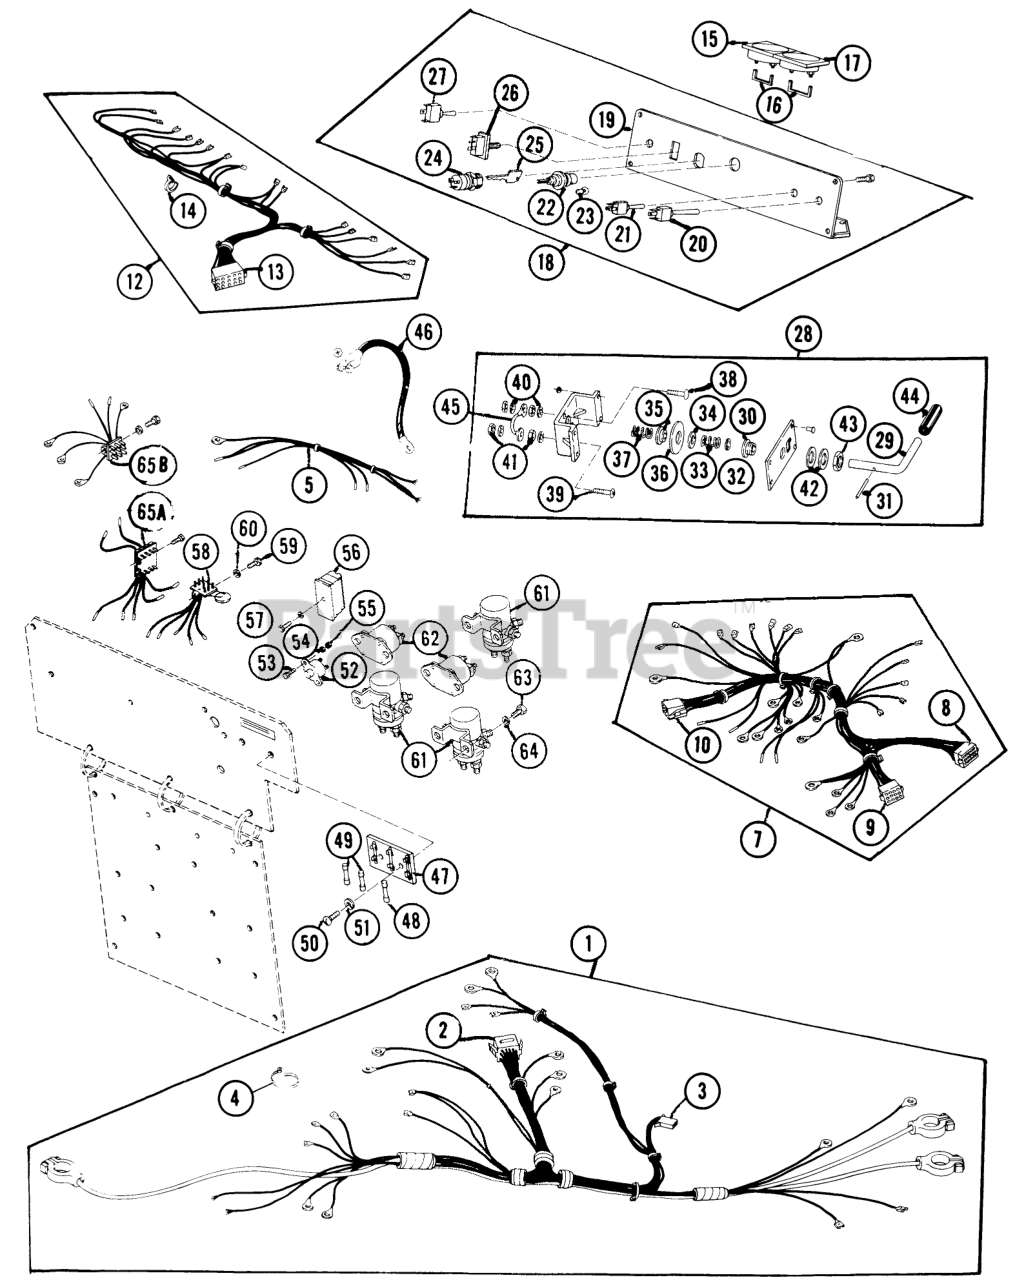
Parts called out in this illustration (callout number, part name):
11-01	Chassis Wiring Harness (Complete)
11-02	Socket Housing (J3)
11-03	Socket Housing (J7)
11-04	Cable Tie
11-05	Control Panel Adder Wires
11-06	Nut, Hex 5/16-18
11-07	Control Panel Wiring Harness (Complete)
11-08	Socket Housing
11-09	Pin Housing (P1)
11-10	Pin Housing (P3)
11-11	Cable Tie
11-12	Dash Wiring Harness (Complete)
11-13	Pin Housing (P1)
11-14	Cable Tie
11-15	Power Use Gauge
11-16	Bracket
11-17	Fuel Level Meter
11-18	Dash Panel Assembly
11-19	Dash Panel
11-20	Switch
11-21	SWITCH
11-22	Light, Dash Panel
11-23	Bulb, Dash Panel Light
11-24	Key Switch
11-26	Power Pulse Switch
11-27	Light Switch
11-28	Power Disconnect Switch
11-29	Switch Handle
11-30	Bushing
11-31	1/8 X 1 1/4 PIN
11-32	Washer
11-33	Spring
11-34	Fiber Washer
11-35	Fiber Bushing
11-36	Contact Disc
11-37	SPRING
11-38	Contact Bolt (Copper)
11-39	Screw 1/4-20 X 3/4 Brass
11-40	Lockwasher 1/4
11-41	Nut, 1/4-20
11-42	Lockwasher, Int. Tooth 5/8
11-43	Nut, 5/8-18
11-44	Hand Grip
11-45	Fuseable Link
11-46	Battery Cable #1
11-47	Fuse Block
11-48	Fuse (FU-2)
11-49	Fuse, 20A
11-50	Thd. Rolling Screw 6-32 x 1/2
11-51	Lockwasher-#8
11-52	Circuit Breaker
11-53	Screw, Machine, #10-32 x 3/4
11-54	Lockwasher #10
11-55	Nut #10-32
11-56	Relay, RTN
11-57	Screw, Hex Machine #8-32 x 3/8
11-58	Diode & Varistor Assembly
11-59	Screw, Hex Thd. Rolling #6-32 x 3/8
11-60	Lockwasher #6
11-61	PTO Contactor
11-62	Power Contactor 1A, 2A
11-63	Screw, Thd. Rolling #10-32 x 3/8
11-64	Lockwasher 1/4
11-65A	Field Resistor Assembly
11-65B	Diode Assembly
11-69	Battery Post Clamp (+)
11-70	Battery Post Clamp (-)
11-71	Wire, #6 AWG
11-122	Screw, Thrd. Rolling #8-32 x 1/2 Dull Black
11-125	Brake Switch
11-126	Mach. Screw #10-32 x 3/4
11-127	Lockwasher
11-128	Jumper Wire #52
